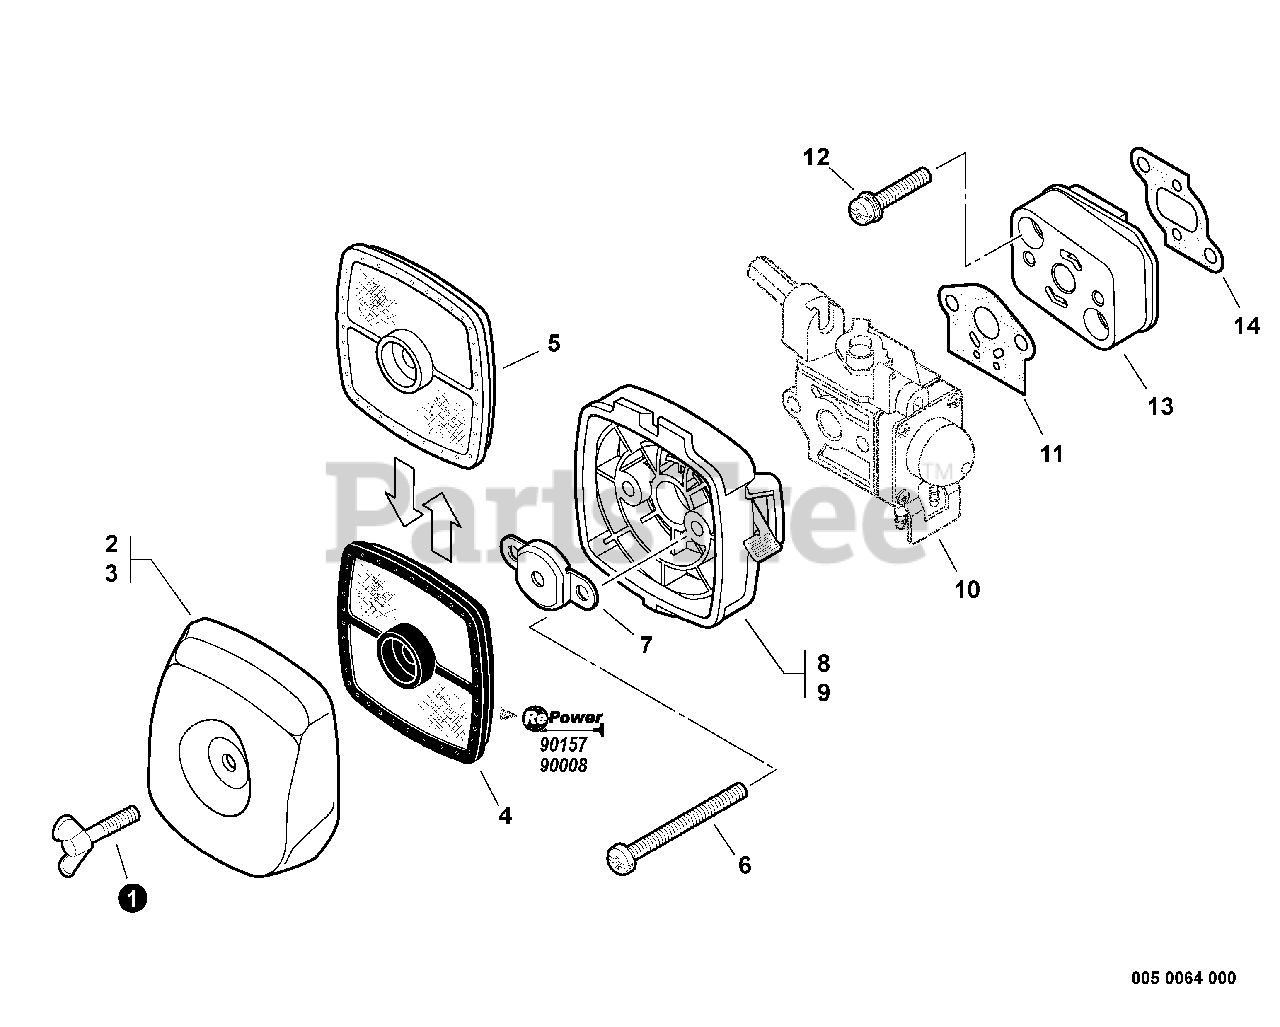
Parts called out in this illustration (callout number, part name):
1	THUMBSCREW
2	COVER, AIR FILTER - GRAY
3	COVER, AIR FILTER - BLACK
4	FILTER, AIR - DOUBLE LAYER
5	FILTER, AIR - SINGLE LAYER
6	SCREW - 5X60
7	PLATE, PREVENT
8	CASE, AIR FILTER - GRAY
9	CASE, AIR FILTER - BLACK
10	CARBURETOR
11	GASKET, INTAKE
12	SCREW - 5X25
13	INSULATOR, INTAKE
14	GASKET, INTAKE
15	RePower TUNE-UP KIT
16	RePower FILTER KIT
